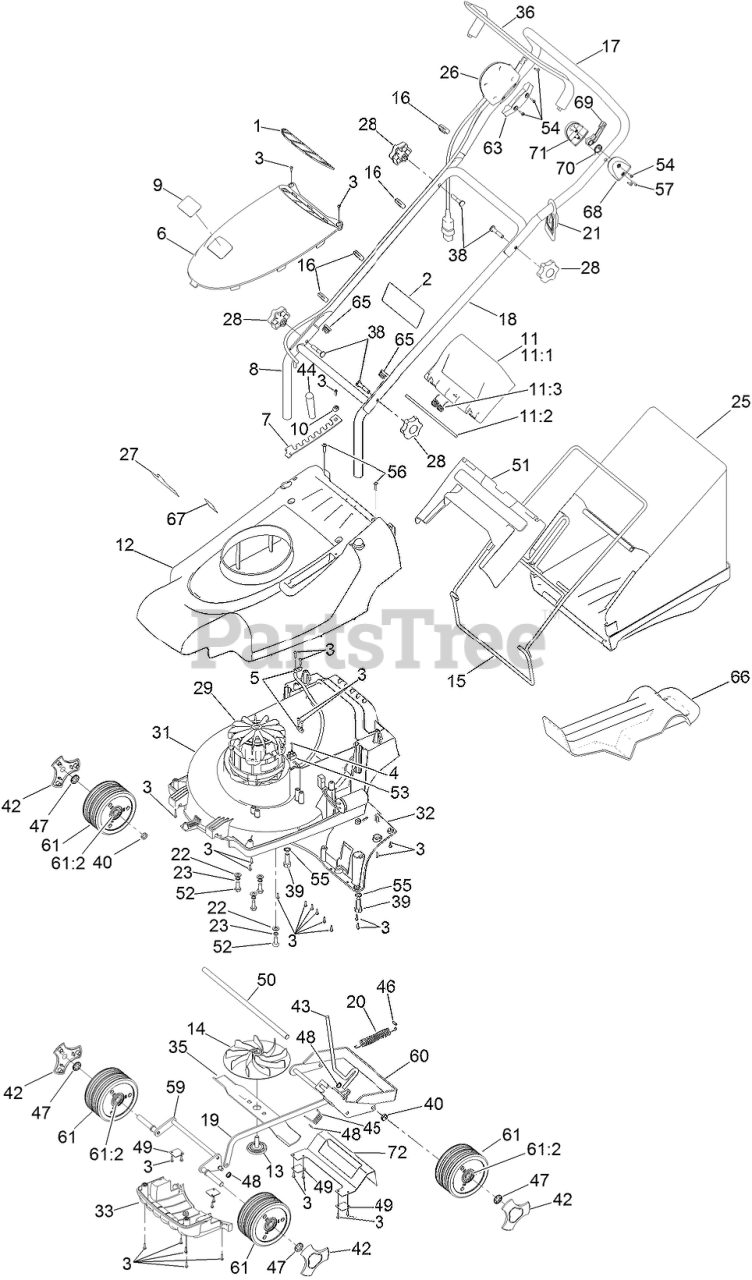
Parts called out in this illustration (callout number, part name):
1	VENT MESH ASM
2	DECAL-SAFETY, ELECTRIC
5	CLAMP-CABLE
6	COVER-MOTOR
7	PLATE-HOC
8	HANDLEBAR-LOWER
9	DECAL-TORO
10	COVER-SCREW, HOC
11	Rear Flap ASM
11:1	DEFLECTOR-REAR
11:2	ROD-DEFLECTOR
11:3	SPRING-DEFLECTOR
12	COVER-TOP
13	BOLT-FIXING, CUTTERBAR (NYLON)
14	CARRIER-CUTTERBAR
15	FRAME-GRASSBAG
16	CLIP-CABLE
17	HANDLEBAR-UPPER
18	HANDLEBAR-MIDDLE
19	ROD-CONNECTING
20	SPRING-BALANCE, COUNTER
21	CLEAT-CABLE
22	WASHER
23	WASHER-SPRING
25	GRASSBAG
26	SWITCH AND LEAD ASM
28	KNOB-HANDLEBAR
31	UNDERDECK
32	THROWPLATE
35	CUTTERBAR
36	ARM-BAIL
38	BOLT-HANDLEBAR
39	SCREW-HH
40	SPACER-WHEEL, REAR
42	CAP-HUB
43	LEVER-HOC
44	KNOB-HOC
45	SPRING-HOC
46	PIN-SPRING, HOC
47	WASHER-STARLOCK
48	WASHER-STARLOCK
49	PLATE-PIVOT, AXLE
50	ROD-AXLE, REAR
51	TOP-GRASSBAG
52	BOLT-MOTOR
53	BLOCK-TERMINAL
55	WASHER
56	SCREW
57	SCREW-PPH
59	FRONT AXLE ASM
60	REAR AXLE ASM
61	WHEEL ASM
61:2	BEARING-WHEEL
63	SWITCH-LEFT, LOWER
65	PLUG-TUBE
66	PLUG-MULCHING
67	DECAL-HOC
68	MOUNT-LEFT
69	LEVER-MOUNT
70	SPRING-BAILARM
71	MOUNT-RIGHT
72	GUARD-PLATE, AXLE
